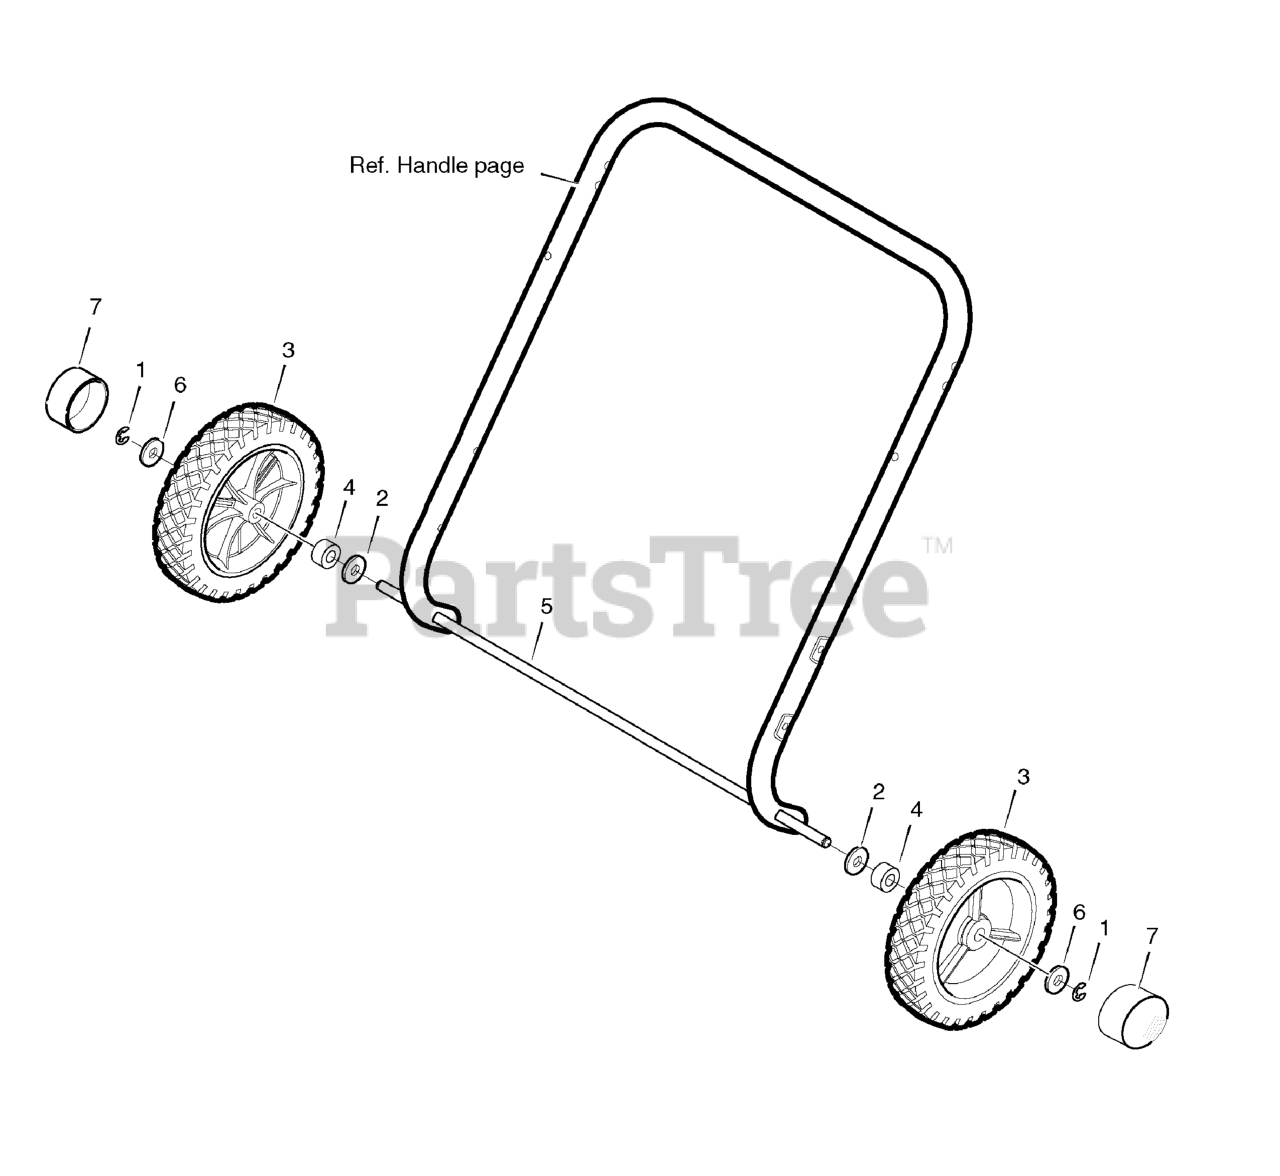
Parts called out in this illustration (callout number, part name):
1	Retainer, E-Ring
2	WASHER, Flat, 13/32
3	Wheel and Tire 7" x 1.50"
4	Sleeve, Spacer
5	Rod, Axle
7	Cap, Hub
